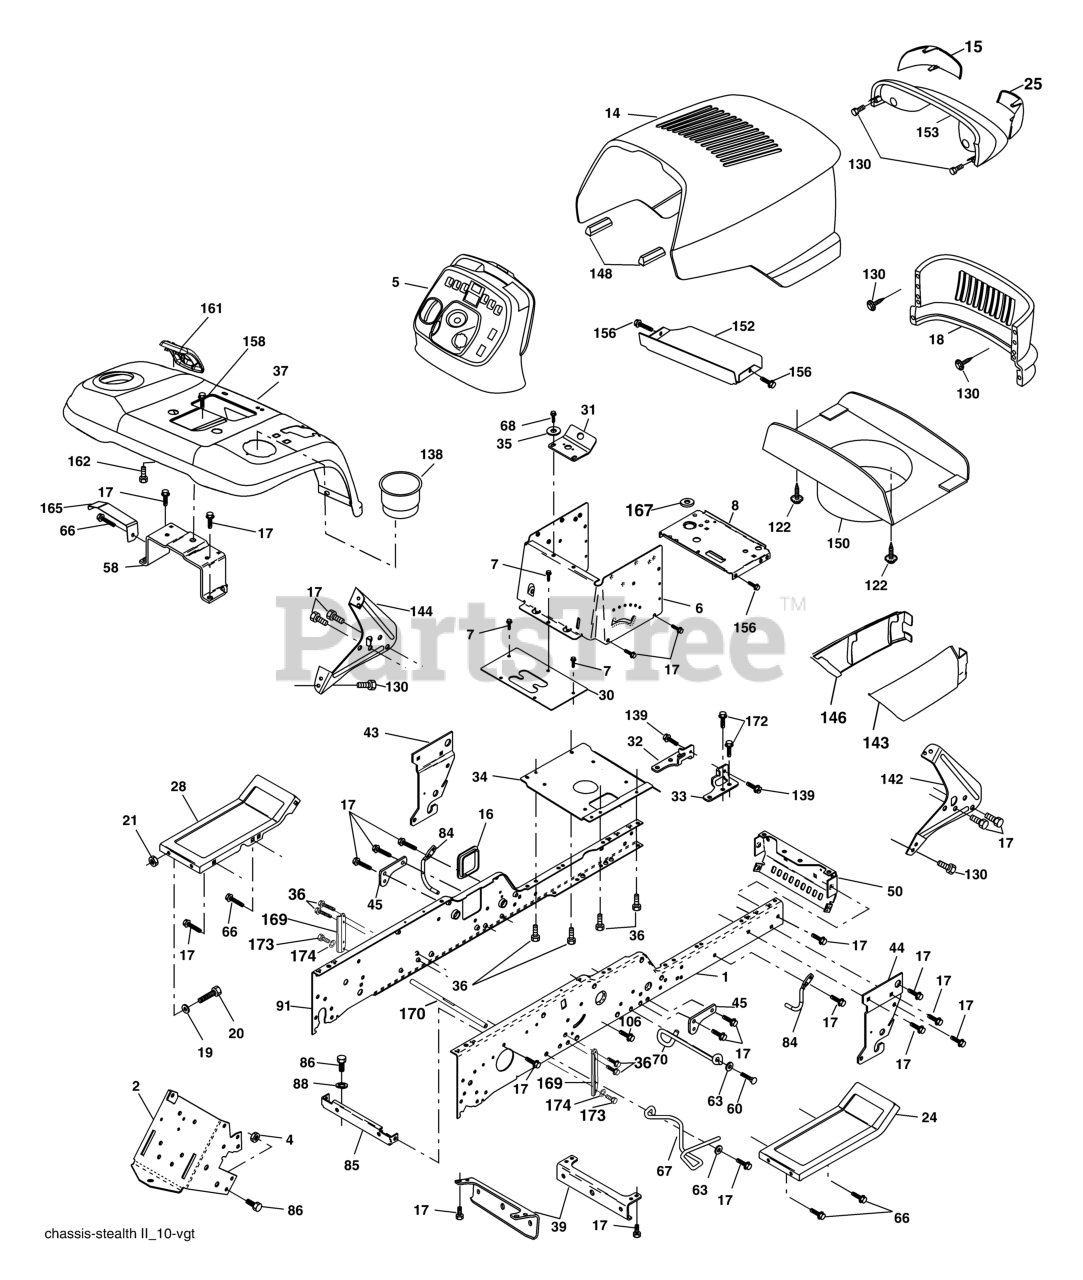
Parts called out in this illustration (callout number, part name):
1	KIT.RAIL.CHASS.RH.GT
2	DRAWBAR, GT
4	Nut, Crownlock Hex 7/16-14 unc
5	DASH STEALTH
6	DASH VGT, LOWER
7	SCREW
8	SUPPORT, BATTERY
14	HOOD
15	LENS LH
16	COVER ACCESS
17	SCREW, 3/8-16X3/4
18	GRILLE.STEALTH P/L.YTGT.GREY
19	WASHER
20	BOLT
21	NUT
24	FOOTREST PNT RH
25	LENS RH
28	FOOTREST PNT LH
31	BRACKET SUPT 1-PC VGT STEERING
34	PLATE ASM ENG CHASSIS
35	WASHER
36	SCREW 5/16"
37	FENDER.PNT.YTGT.WO/SHF.ORANGE
39	BRACKET AXLE, FRONT
43	FRONT SUSPENSION BRKT LH
44	FRONT SUSPENSION BRKT RH
45	BRACKET ARM SUSPENSION
50	BRACKET, CHASSIS FRONT
58	BRACKET ASM., FENDER
60	SCREW.3/8-16
63	WASHER
66	SCREW LT
67	GUIDE.BELT.TRANSAXLE.GEAR.DRIV
68	Screw Thdrol. 5/16-18 x 1/2
70	GUIDE.BELT.MID.SPAN.54"
84	UPSTOP 54"
85	BRKT.SUPPT
86	BOLT FIN HEX 7/16-14 X 1
88	LOCKWASHER
91	KIT.RAIL.CHASS.LH.GT
106	BOLT.5/16-18X1.25
122	SCREW.WSHD.HEX10-32X5/8
130	SCREW
137	BOLT FIN HEX 7/16-14 X 1
138	CUPHOLDER.YTGT
139	BOLT, SHOULDER 5/16-18
142	BRACKET DASH STEALTH(R)
143	SKIRT GRILLE RH
144	BRACKET DASH STEALTH LH
146	SKIRT GRILLE LH
148	EXTRUSION BUMPER (3 2) (2 2)
150	DUCT.HEAT.HOOD.STEALTH.GT
152	BROWNING SHIELD
153	LIGHTBOX.ASM.STV.DL.INC.HUSQ
156	SCREW
158	SCREW 3/8-16X1/2
161	CONSOL.FUEL.WINDOW.BLACK
162	SCREW.HI-LO.CONSOLE
165	BRACKET SUPPORT TANK
169	BRACKET CHASSIS SWAY
170	ROD.BRKT.SWAY
171	BUSHING SNAP
172	SCREW 3/8-16X.875
173	BOLT.FIN.HEX.5/16-18X3/4
174	WASHER.LOCK.HVY.HLCL.SPR.5/16
